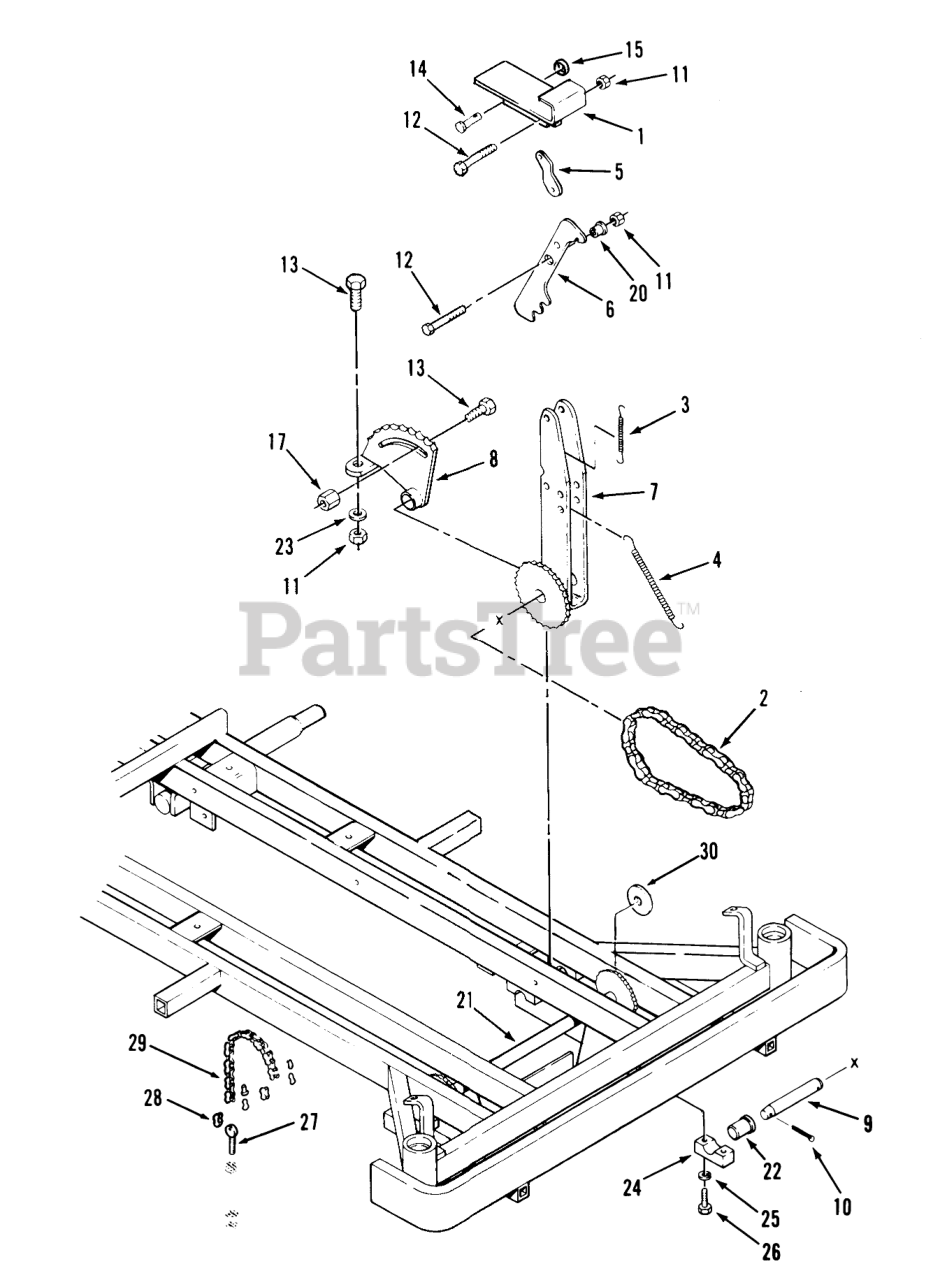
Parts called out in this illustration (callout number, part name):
1	PEDAL-FOOT 10218- B
2	CHAIN-FOOT PEDAL DR
3	SPG-NEUTRAL 20217-35
4	SPRING - EXTENSION
5	PIVOT-LINK B
6	LIFT-ARM PWL B
7	ASSY-LVR ARM 1022 B
8	HEIGHT CONTROL SP B
9	PIN-PEDAL
10	PIN-COTTER
11	NUT-LOCK, NI
12	SPIROL PIN H D
13	SCREW-HH
14	PIN-LOCK
15	E RING
17	HEX-STOP NUT N-140
20	BUSHING-PDL
21	ASM-Sprocket
22	BEARING-FLANGED
23	WASHER-PLAIN
24	Clamp-Cross Shaft (Incl. w/frame)
25	Washer-Lock 3/8 (Incl. w/frame)
26	Bolt (Incl. w/frame)
27	EYE-BOLT 3/8-16X2.50
28	MASTER LINK CHAIN
29	CHAIN-DECK LIFT
30	Washer
